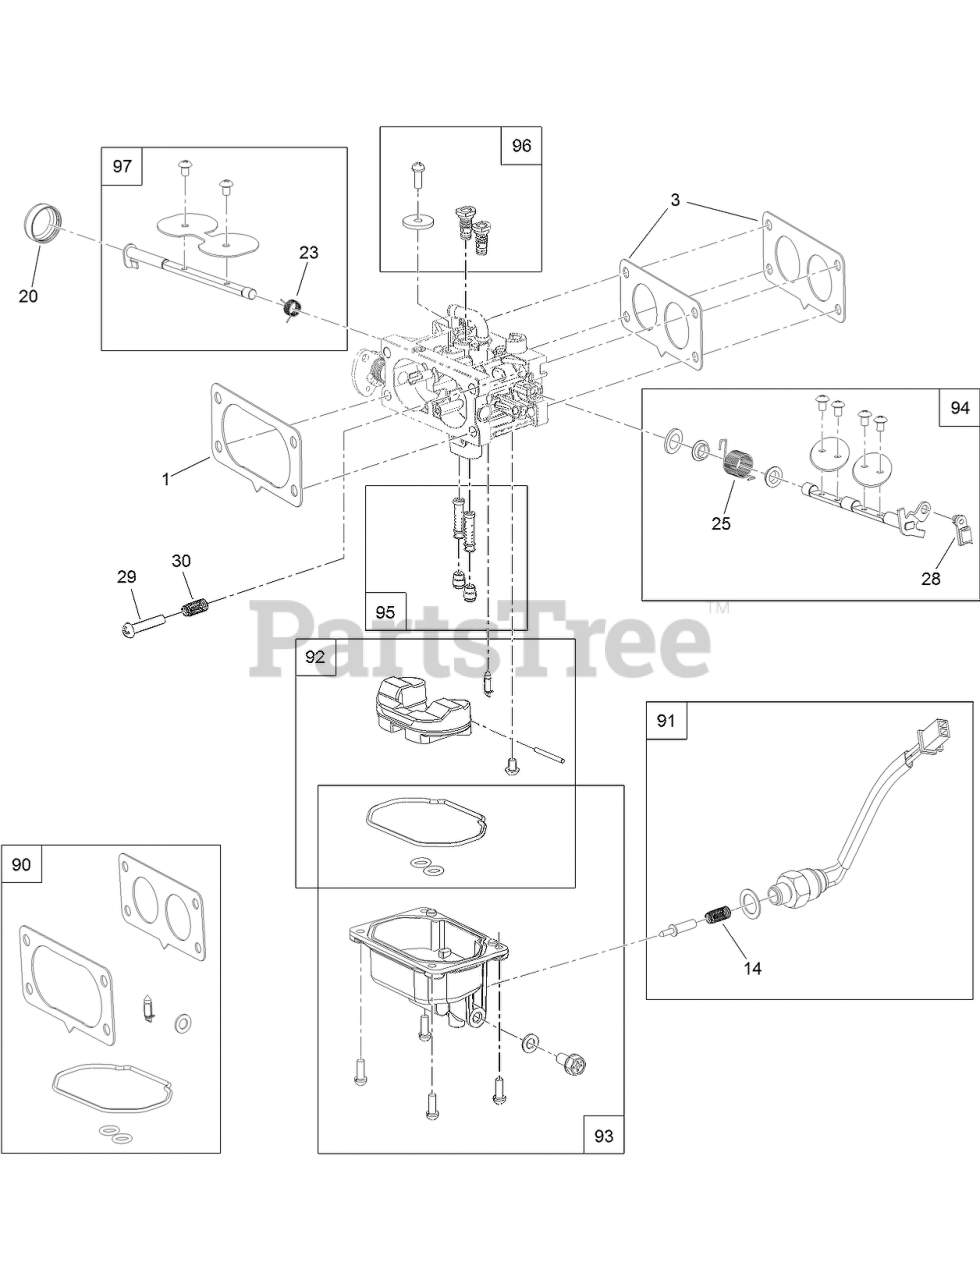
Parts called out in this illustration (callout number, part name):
1	GASKET-CARBURETOR
3	GASKET-CARBURETOR
14	SPRING
20	COVER-SHAFT, CHOKE
23	SPRING
25	SPRING
28	CLAMP-LOCK
29	SCREW-PPH
30	SPRING
90	CARBURETOR REPAIR KIT
91	SOLENOID KIT
92	FLOAT KIT
93	BOWL KIT
94	THROTTLE SHAFT KIT
95	NOZZLE AND JET KIT
96	AIR JET KIT
97	CHOKE SHAFT KIT
